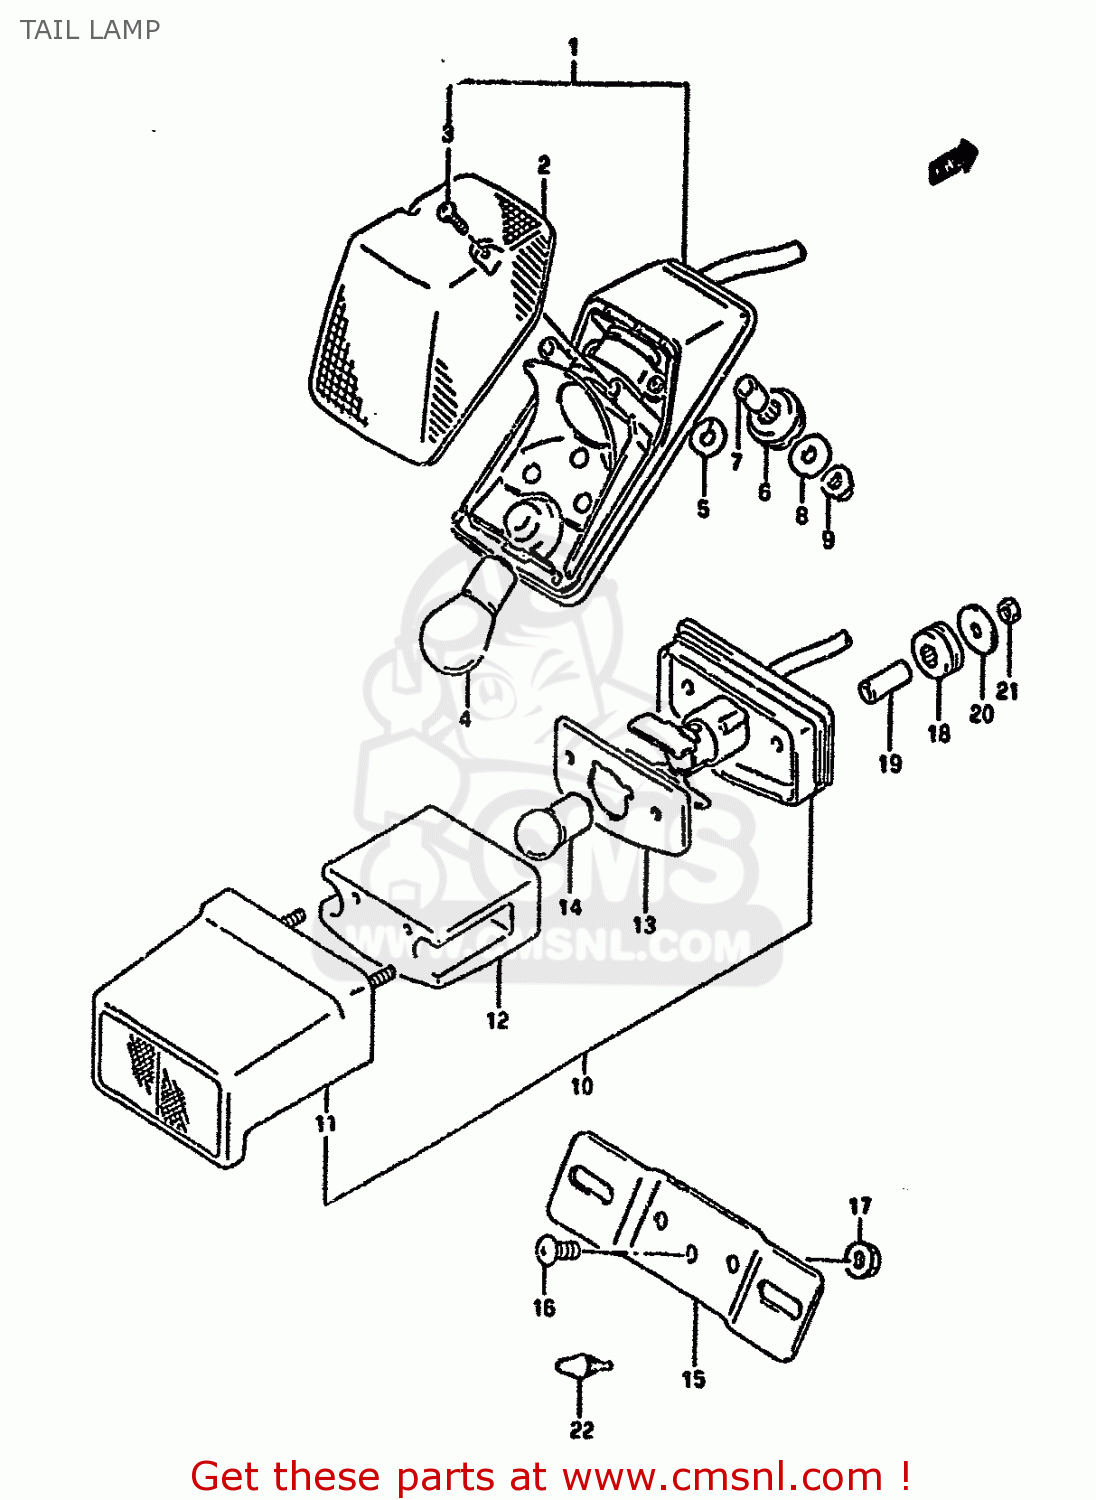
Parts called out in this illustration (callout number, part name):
1	LAMP ASSY,TAIL
2	LENS
3	SCREW
4	BULB(12V21/5W)
5	GASKET (NAS)
6	CUSHION
7	SPACER(6.4X9.2X12)
8	WASHER (6.5X20X1.6)
9	NUT
10	LAMP ASSY,LICENSE
11	REFLECTOR/COVER
12	LENS
13	GASKET,LICENSE LAMP (NAS)
14	BULB(12V5W,BF150-40160A)
15	PLATE,RR LICENSE
16	SCREW
17	NUT
18	CUSHION
19	SPACER (5.5X9.5X19.50)
20	WASHER (5.1X20X1.4)
21	NUT 5MM
22	CUSHION
